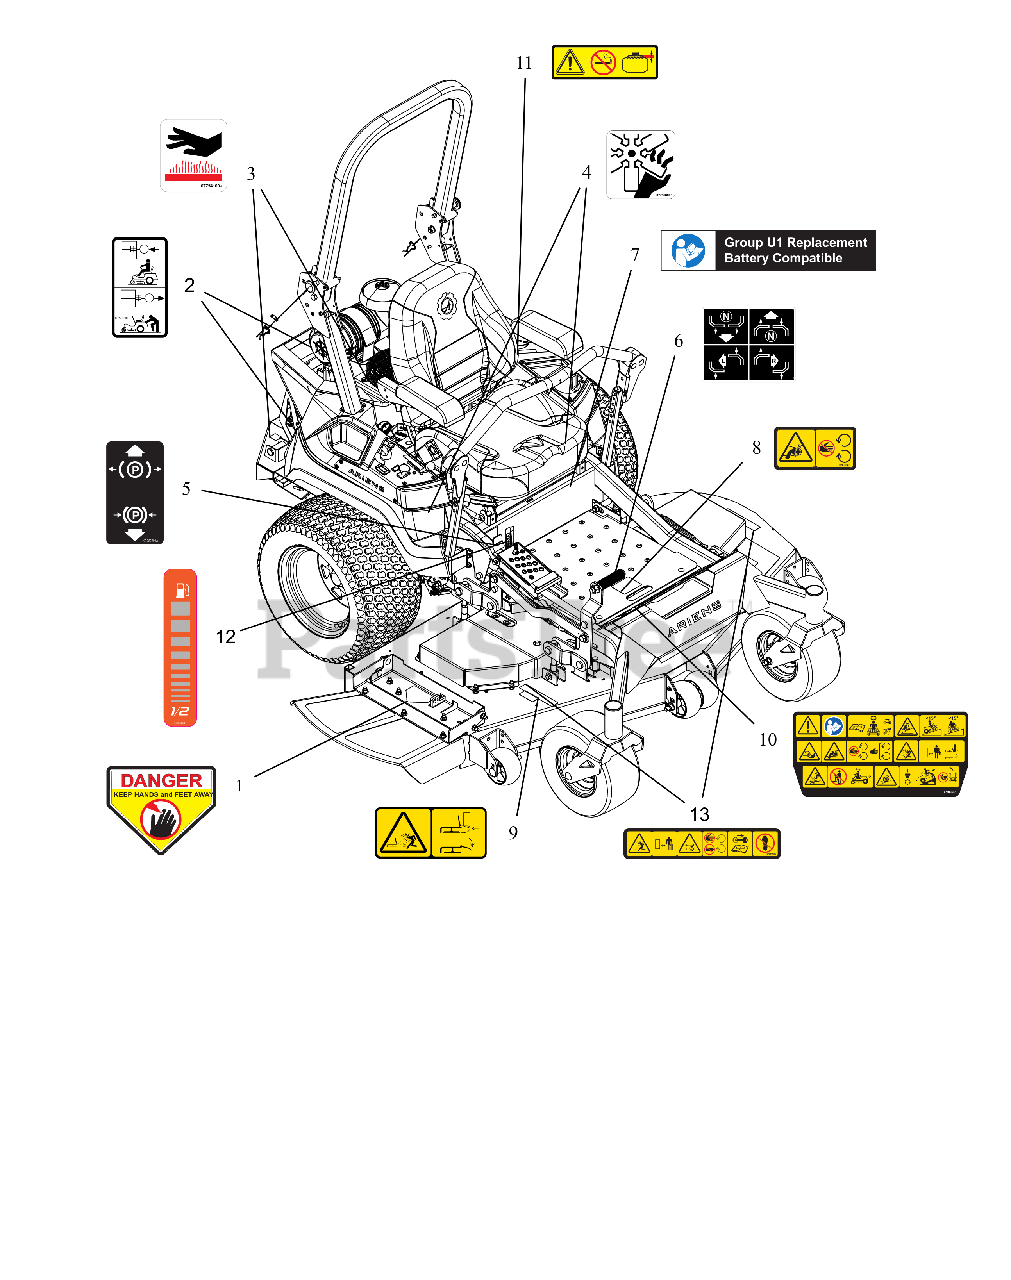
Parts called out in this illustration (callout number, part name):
1	DECAL, DANGER
2	DECAL, TRANSMISSION DISCONNECT
3	DECAL, HOT SURFACE
4	DECAL, DANGER FAN
5	DECAL, PARKING BRAKE LEVER
6	DECAL, INSTRUCTIONAL-STEERING
7	DECAL, U1 BATTERY REPLACEMENT
8	DECAL, SAFETY - GUARDING
9	DECAL, SAFETY - DECK GUARDING
10	DECAL, MAIN SAFETY
11	DECAL, FUEL WARNING
12	DECAL, ARIENS FUEL LEVEL
13	DECAL, DECK SAFETY
